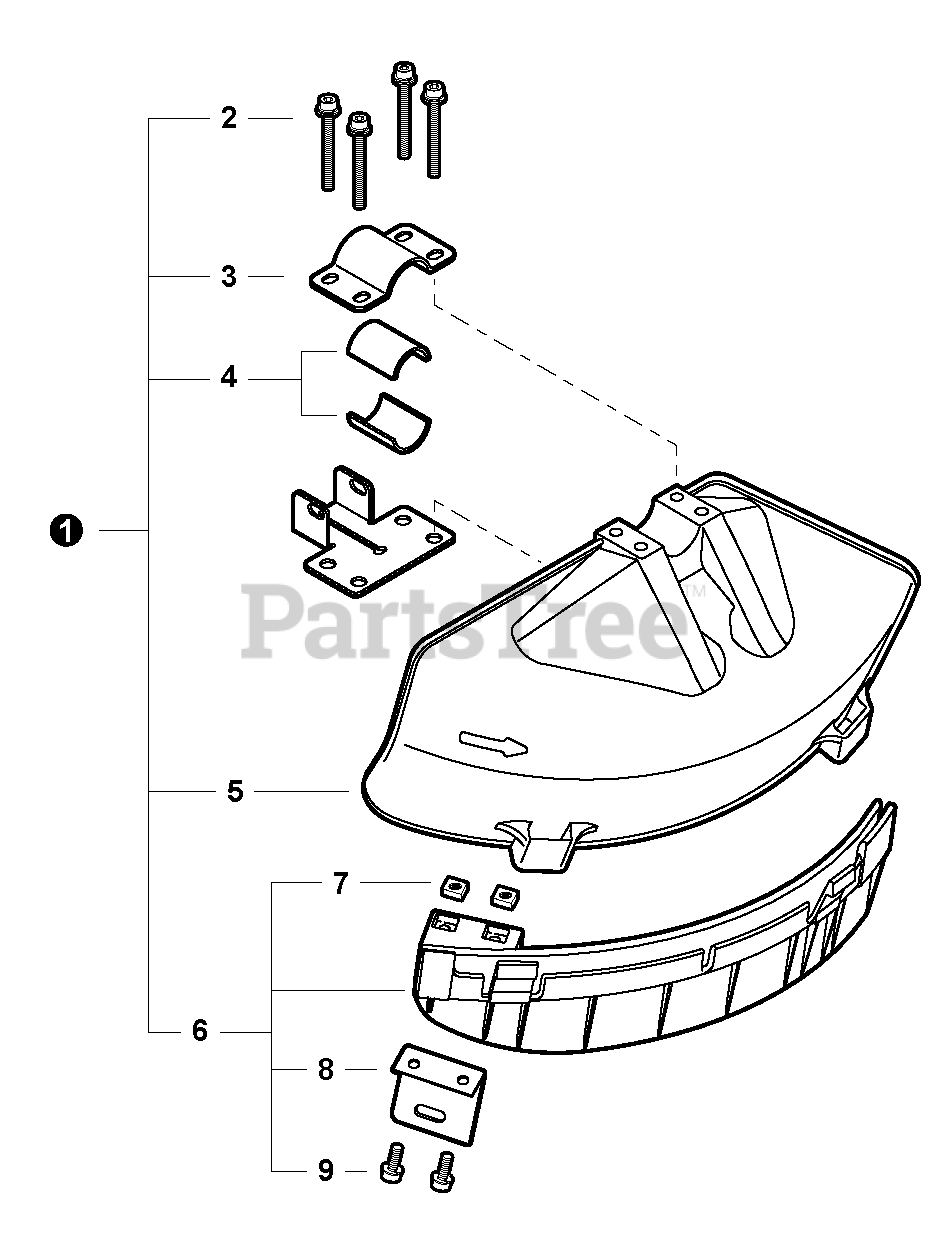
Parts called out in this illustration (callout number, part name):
1	Debris Shield Kit
2	Bolt M5x45
3	Clamp, Upper
4	Spacer 26
5	Shield, Debris Plastic
6	Debris Shield Extension Assy
9	Bolt M5x16
